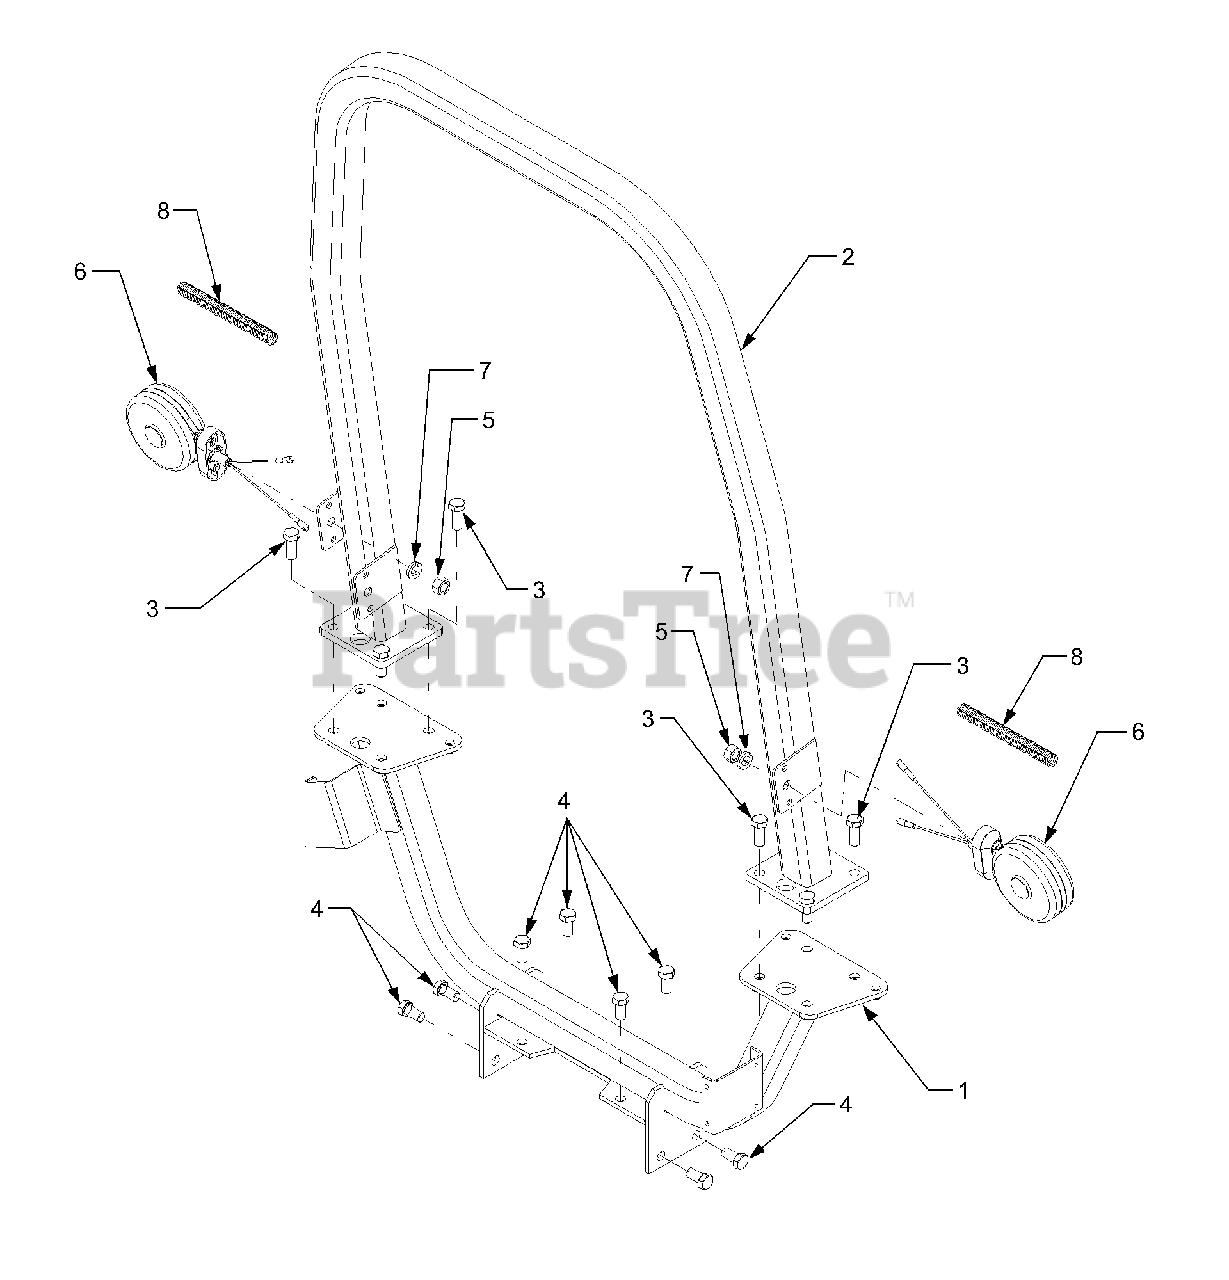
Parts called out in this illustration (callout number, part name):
1	ROPS Assembly, Lower
2	ROPS Assembly, Upper
3	Screw, Hex Cap, 1/2-13 x 1.25 GR5
4	Screw, Hex Cap, /12-13 x 1.0 GR5
5	Nut, Hex, 1/2-13 GR5
6	Light Assembly, Hazard
7	Washer, Lock, 1/2
